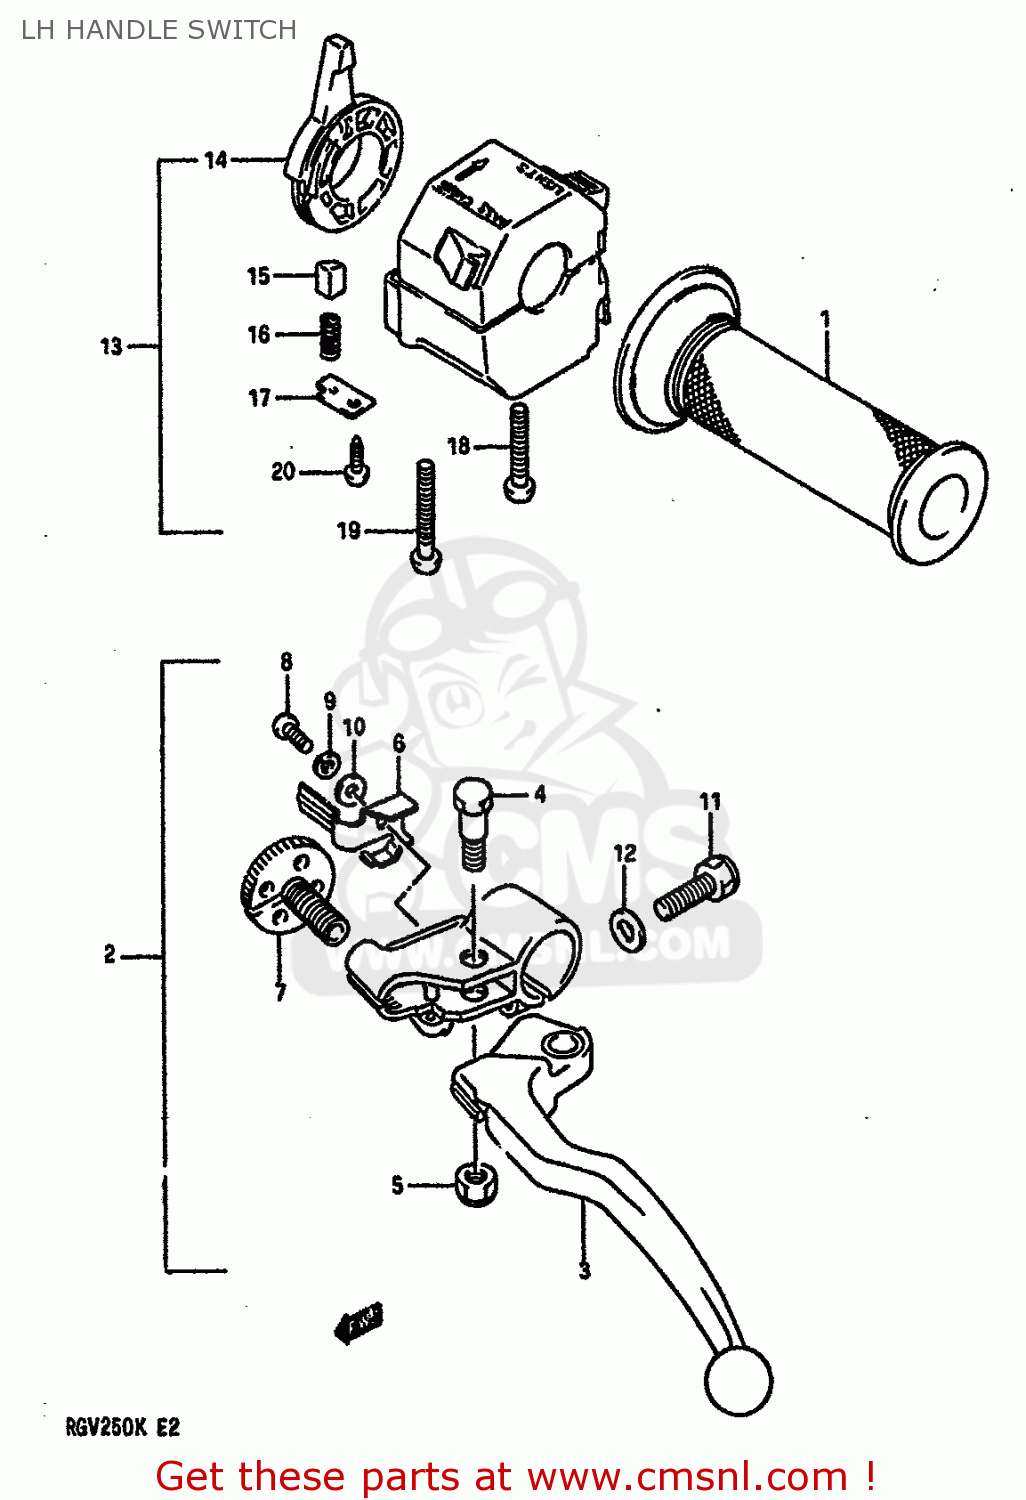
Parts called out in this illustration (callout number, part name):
1	GRIP,L
2	LEVER ASSY, CLUTCH
3	LEVER,CLUTCH
4	BOLT,LEVER PIVOT
5	NUT
6	ADJUSTER,SPRING
7	ADJUSTER,LOCK
8	SCREW
9	LOCK WASHER
10	WASHER
11	BOLT
12	WASHER
13	SWITCH ASSEMBLY,HANDLE,LEFT
14	LEVER,CHOKE
15	PIECE,SLIDE
16	SPRING
17	PLATE
18	SCREW
19	SCREW, 5X45
20	SCREW
